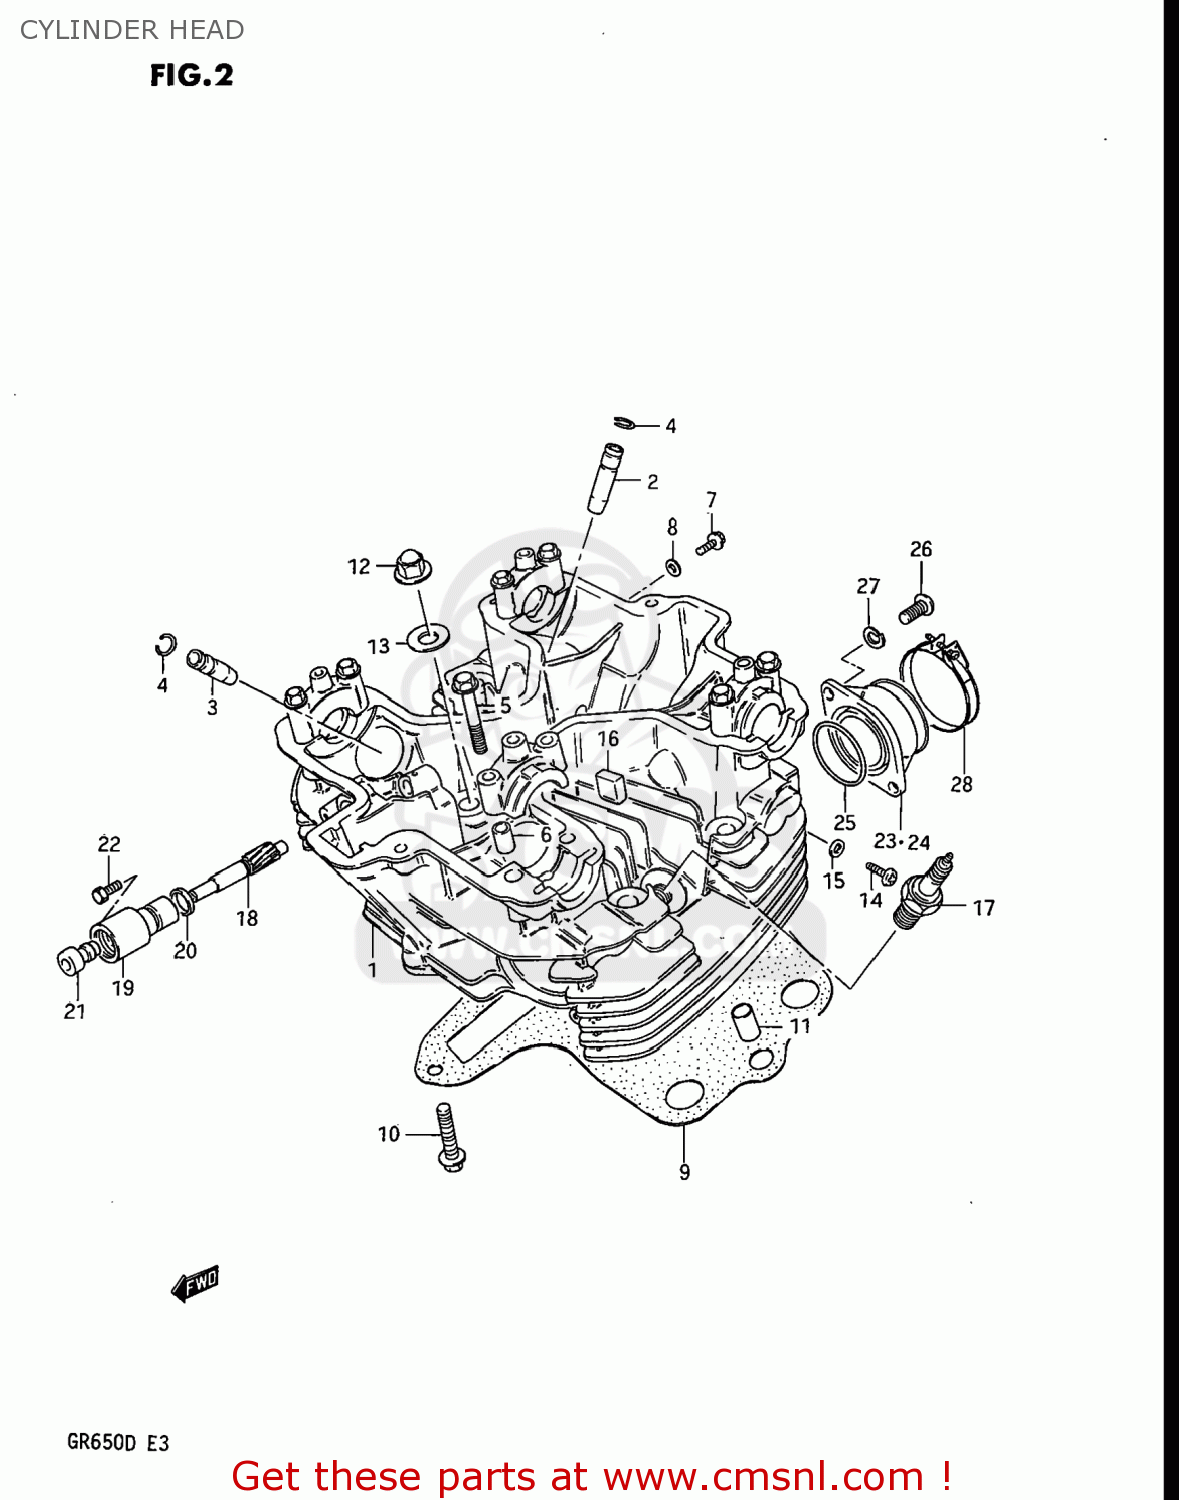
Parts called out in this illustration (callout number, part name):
1	HEAD,CYLINDER
2	GUIDE,INTAKE VALVE
3	GUIDE,EXHAUST VALVE
4	RING,SNAP
5	BOLT(6X39)
6	PIN(6.2X8X11)
7	BOLT 6X12
8	GASKET (NAS)
9	GASKET,CYLINDER HEAD
10	BOLT
11	PIN
12	NUT
13	GASKET (NAS)
14	SCREW
15	GASKET(5.3X9.3X1.2) (NAS)
16	PAD,CYLINDER HEAD
17	SPARK PLUG D8EA
18	GEAR,TACHOMETER DRIVEN
19	SLEEVE
20	SEAL,TACHOMETER DRIVEN
21	SEAL,OIL(5X12X8)
22	SCREW(5X12)
23	PIPE,INTAKE,R
24	PIPE,INTAKE,L
25	O-RING (D:2.4 ID:39.7)
26	SCREW
27	LOCK WASHER
28	CLAMP
